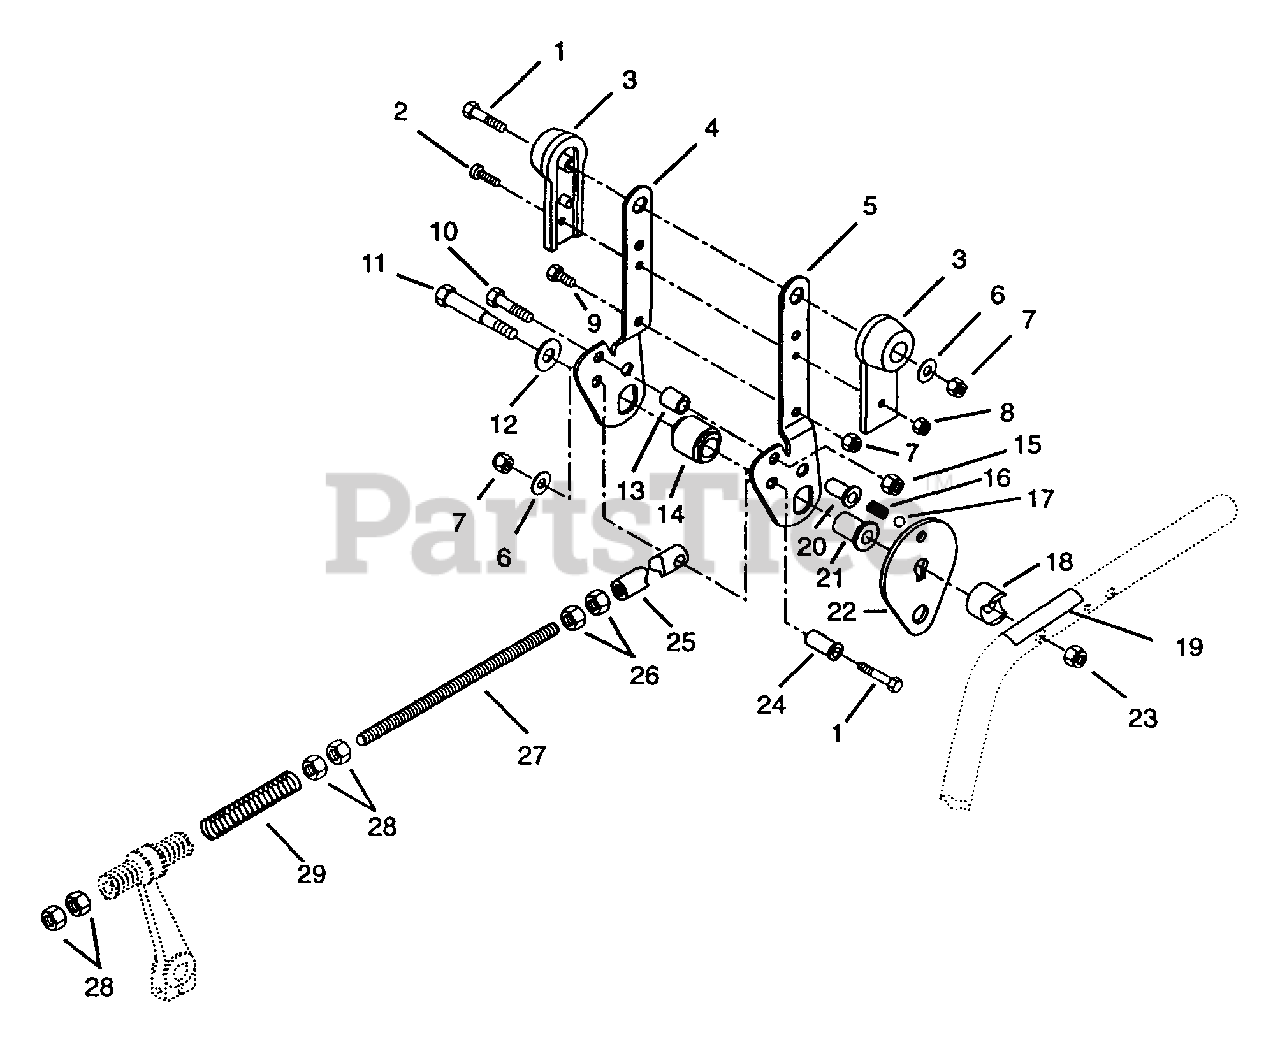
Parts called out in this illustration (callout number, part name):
1	Bolt-Hex .25-20 x 1.50 Grade 5
2	Screw-Machine 6-32 x .625
3	Knob, Handle Control
4	Handle, Control Right Hand
5	Handle, Control Left Hand
6	Washer-Flat-Steel .261 x .620 x .065
7	Nut-Locking-Nylon .250-20 Grade 2
8	Nut-Locking-Machine 6-32
9	Bolt-Hex .25-20 x .63
10	Bolt-Hex .38-16 x 1.50 Grade 5
11	Bolt-Hex .38-16 x 3.5
12	Washer-Flat-Steel .531 x 1.062 x .095
13	Sleeve, Handle Stop
14	Bushing Flange .751 x 1.13 x 1.07
15	Nut-Locking-Nylon .375-16 Grade 2
16	Spring-Compression .038 x .281 x .88
17	Ball, .312 Guard 2000
18	Bracket, Handle Pivot
19	Decal, Forward-Reverse
20	Bushing-Flange .320 x .750 x 1.280
21	Bushing-Flange .515 x .746 x 1.290 x 1.000
22	Plate, Neutral
23	Nut-Locking-Nylon .375-16 Grade 2
24	Bushing-Flange .257 x .38 x 1.080
25	Rod, Control Forward Reverse
26	Nut-Hex.375-16 Grade 2
27	Rod, Extension
28	Nut-Jam .375-16
29	Spring-Compression .072 x .561 x 2.50
